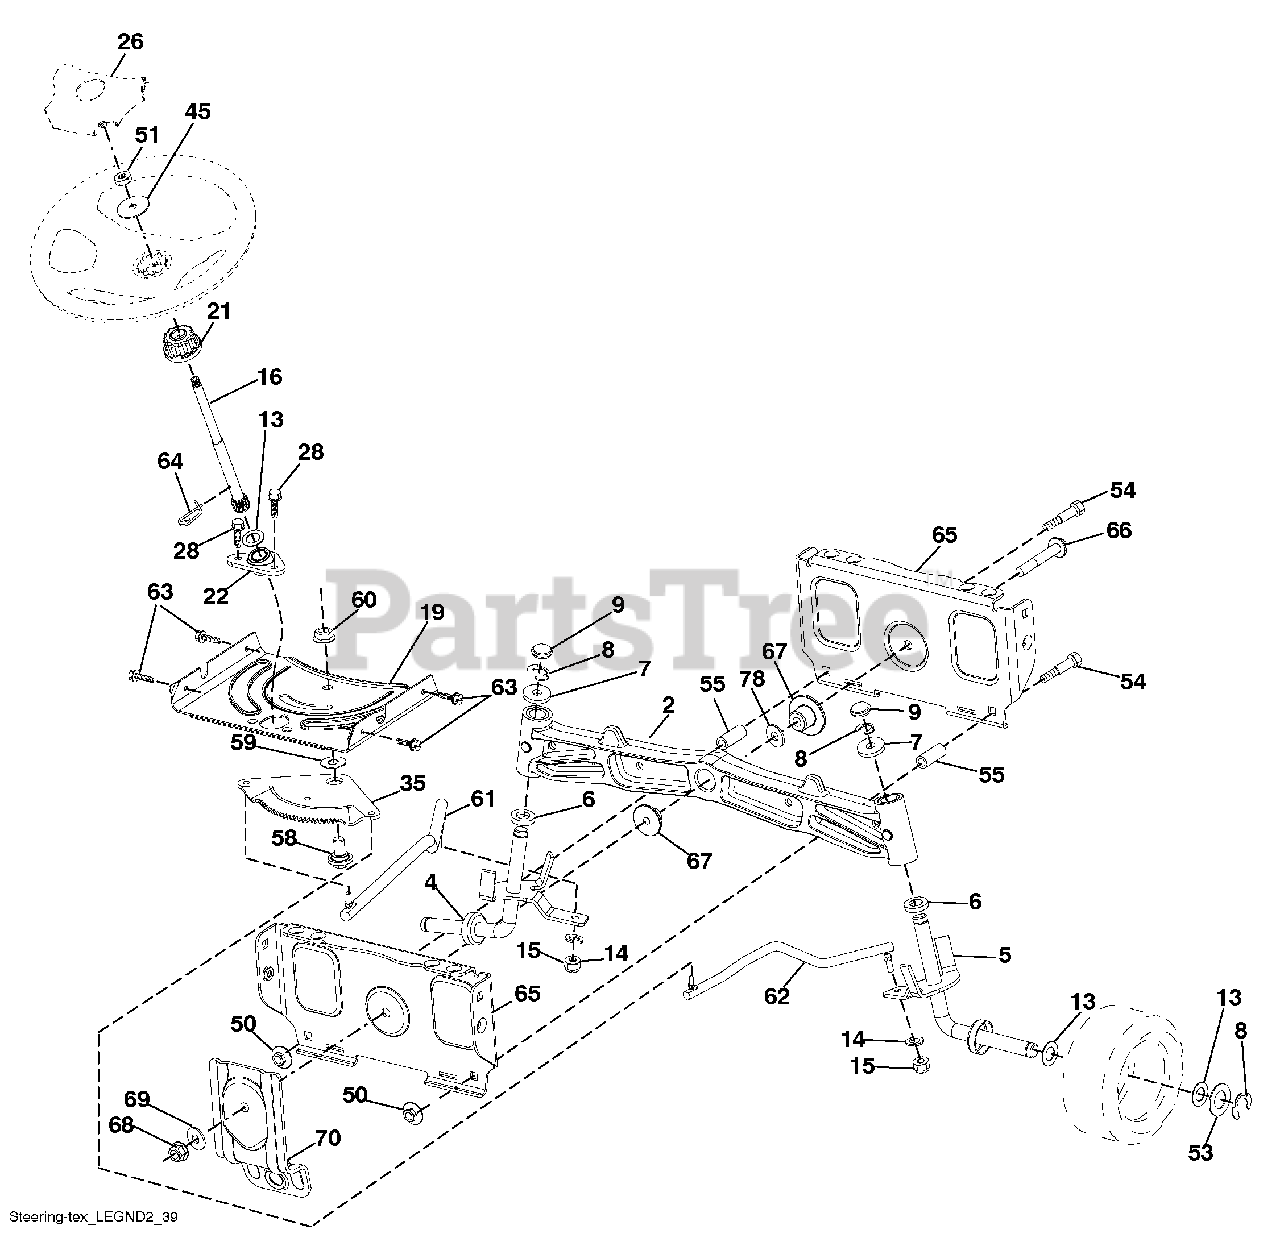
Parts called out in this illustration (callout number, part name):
1	Wheel, Steering
2	Axle Asm., Front
4	Spindle Asm. LH
5	Spindle Asm. RH
6	Bearing, Race Thrust Harden
7	Washer 25/32 x 1-5/8 x 16 Ga.
8	Ring, Clip #T5304-75
9	Cap, Spindle
13	Washer 25/32 x 1-1/4 x 16 Ga.
14	Washer, Lock Hvy Hlcl Spr 3/8
15	Nut, Crown Lock 3/8-24 unf
16	Shaft Steering
19	Plate Steering
21	Adapter, Wheel Steering
22	Steering Support Lower
26	Insert, Wheel Steering
28	Screw 3/8-16 x 3/4
35	Gear, Sector Plate
45	Washer 9/16 x 2-3/8 x 12 Ga.
50	Nut Lock Flange 3/8-16 unc
51	Nut Hex Jam Toplock 1/2-20 unf
53	Washer Hardened .793 x 1.637 x .060
54	Bolt Hex 3/8-16 unc x 2-1/4
55	Bolt Hex 3/8-16 unc x 2-1/4
58	Bolt Shoulder Sector Pivot CFM
59	Washer Thrust Sector Steering
60	Nut Flange Lock 5/8-11
61	Draglink, LH
62	Draglink, RH
63	Screw 5/16-18 x 3/4
64	Retainer Clip Spring Steering
65	Brace Axle Front
66	Bolt Hex Fghd 7/16-14 x 3 Serr
67	Bushing PM Front Axle
68	Nut Lock Flange 7/16-14 Gr. 5
69	Washer 1.5 x .505 x .118
70	Bracket Deck Susp. Front
78	Washer Thrust
